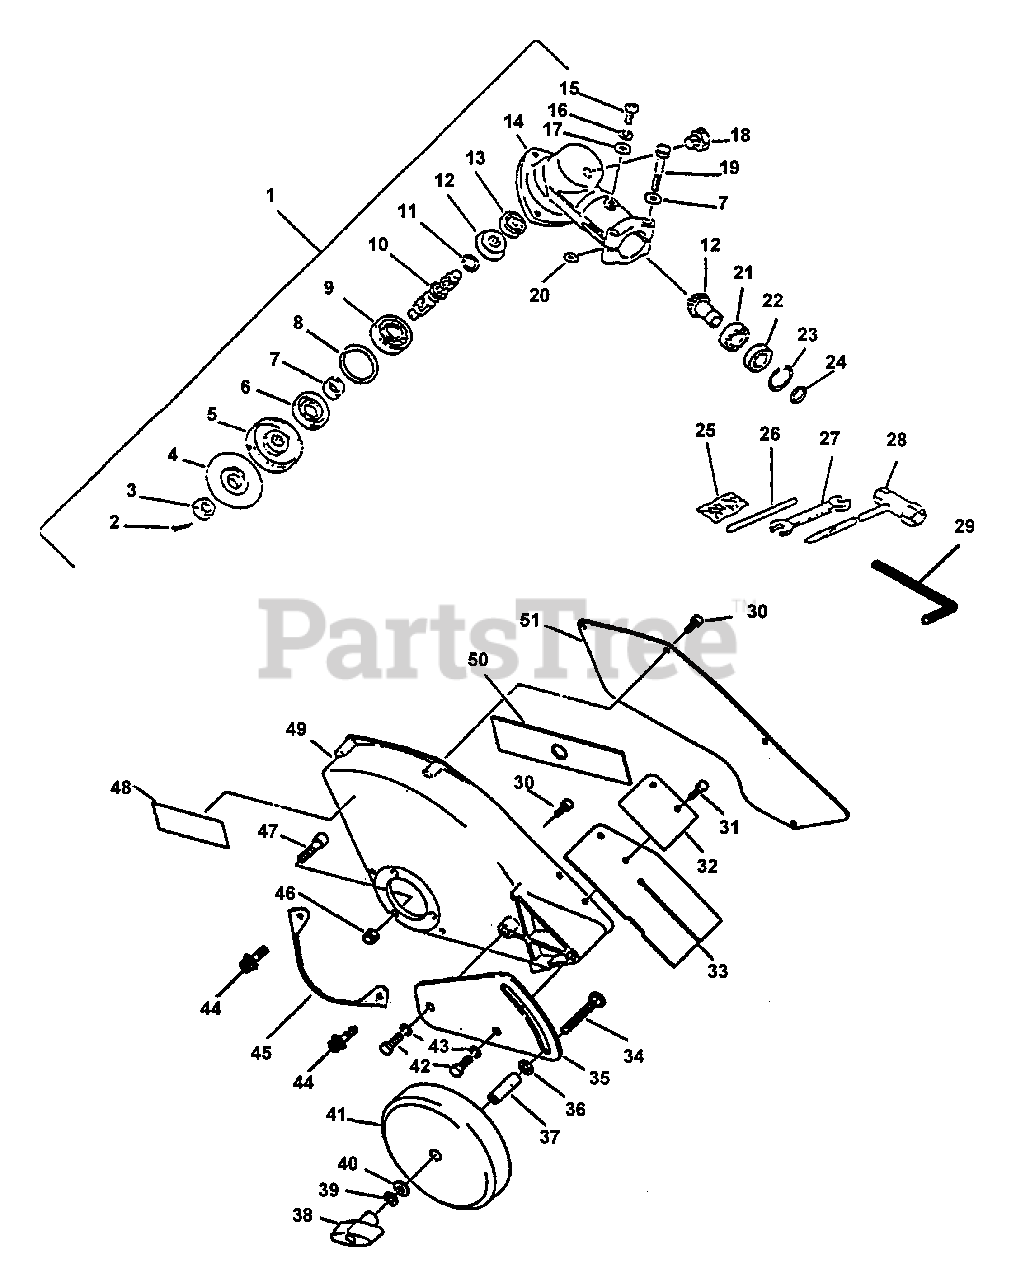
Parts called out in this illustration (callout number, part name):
1	GEAR CASE ASSY
2	PIN, SPLIT - 2X22
3	NUT - 10 -- LEFT HAND
4	ADAPTOR, BLADE - LOWER
5	ADAPTOR, BLADE - UPPER
6	SEAL, OIL
8	RING, RETAINING - 32
9	BEARING, BALL - 6201
10	GEAR - SHAFT
11	RING, RETAINING - 10
12	GEAR SET - BEVEL
13	BEARING, BALL - 609
14	CASE, GEAR
15	SCREW - 5X10
16	LOCKWASHER - 5
17	WASHER - 5
18	BOLT - 8X8
19	BOLT - 5X35
21	BEARING, BALL - 6900
22	BEARING, BALL - 6900Z
23	RING, RETAINING - 22
24	RING, RETAINING - 12
25	PIN, SPLIT - 2X22
26	LOCKING TOOL
27	SPANNER - 8X10mm
28	T-WRENCH - 17X19mm
29	HEX KEY - 3mm
30	SCREW - 4X10
31	SCREW - 4X14
31	SCREW - 4X10
32	FLAP, DEBRIS
33	FLAP, DEBRIS
34	BOLT - CARRIAGE
35	BRACKET, WHEEL
36	WASHER - 10
37	COLLAR - 12
38	WINGNUT - 5/16-18
39	LOCKWASHER - 8
40	WASHER - 8
41	WHEEL - 6X1.5
42	BOLT - 8X14
42	BOLT - 8
43	LOCKWASHER - 8
44	SCREW - 4X12
44	SCREW - 4X16
47	SCREW - 5X22
48	LABEL - CAUTION
49	NEW BLADE SHIELD
49	SHIELD, DEBRIS
50	BLADE, EDGER
51	COVER, SHIELD
